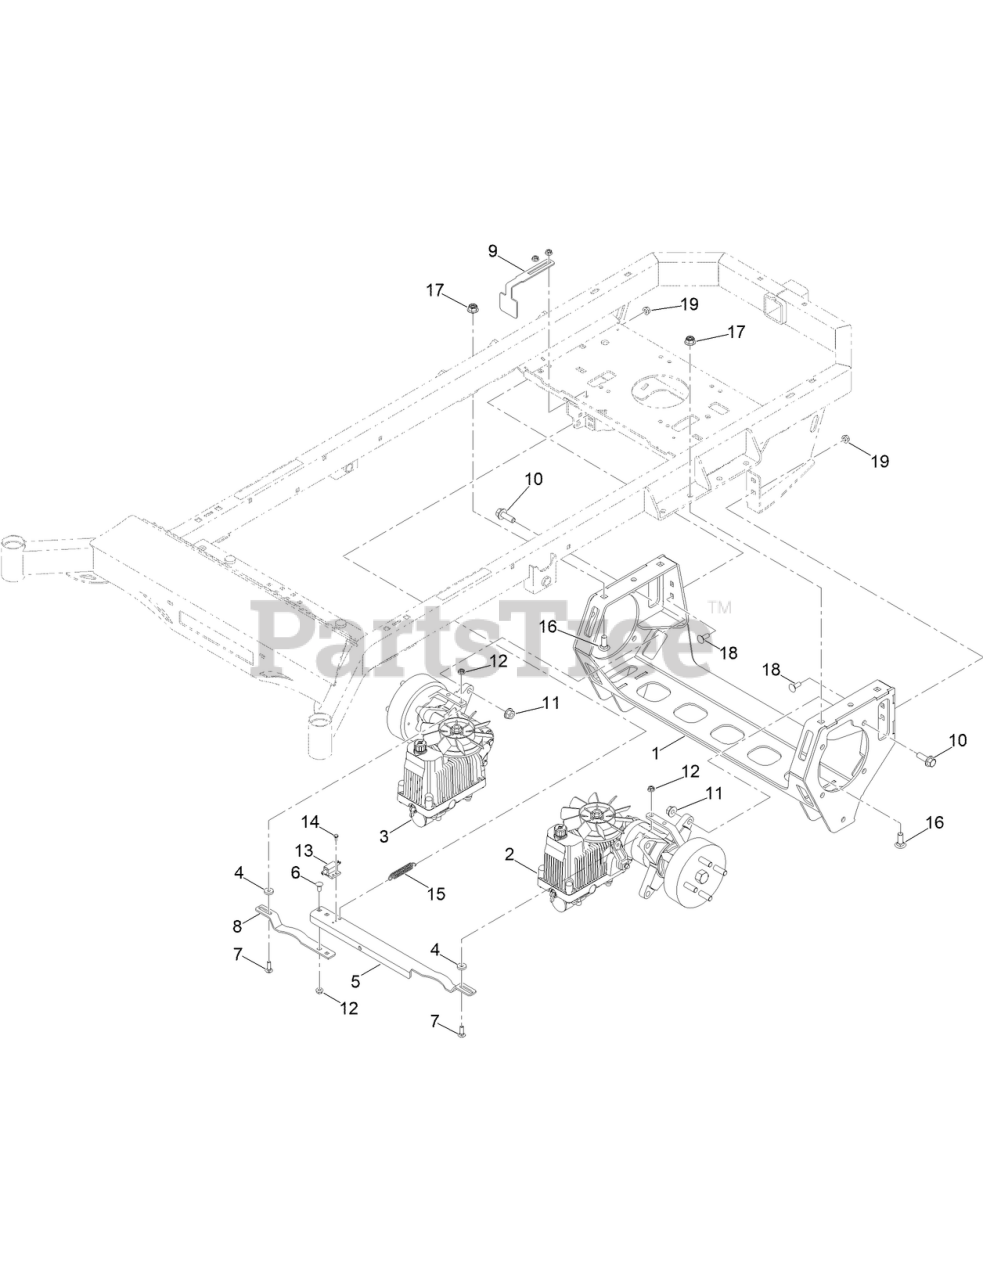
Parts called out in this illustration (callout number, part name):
1	HYDRO FRAME ASM
2	HTE10 LT SIDE HYDROST TRANSM FOR RZ HUB
3	HTE10 RT SIDE HYDROST TRANSM FOR RZ HUB
4	.312 ID X .875OD X .1875 THK F/W NYL
5	MWR PARK BRAKE BRKT LT PAINTD BLACK
6	BOLT-CARR
7	BOLT-CARR
8	MWR PARK BRAKE BRKT RT PAINTED
9	STAND TRANSM BRAKE INTERLOCK BRKT BLACK
10	SCREW-HHF
11	NUT-HHF
13	NO PLUNGER LIMIT SWITCH
14	8-32 X 1/2 IND. HWH SLOT TYPE F TCS ZINC
15	MWR BRAKE PEDAL RELEASE SPRING
16	SCREW-CARR
17	1/2-13 HEX FLANGE 2-WAY REV CNTR L/NYZ
18	3/8-16 X 1 CARRIAGE BOLT YZ GR.8
